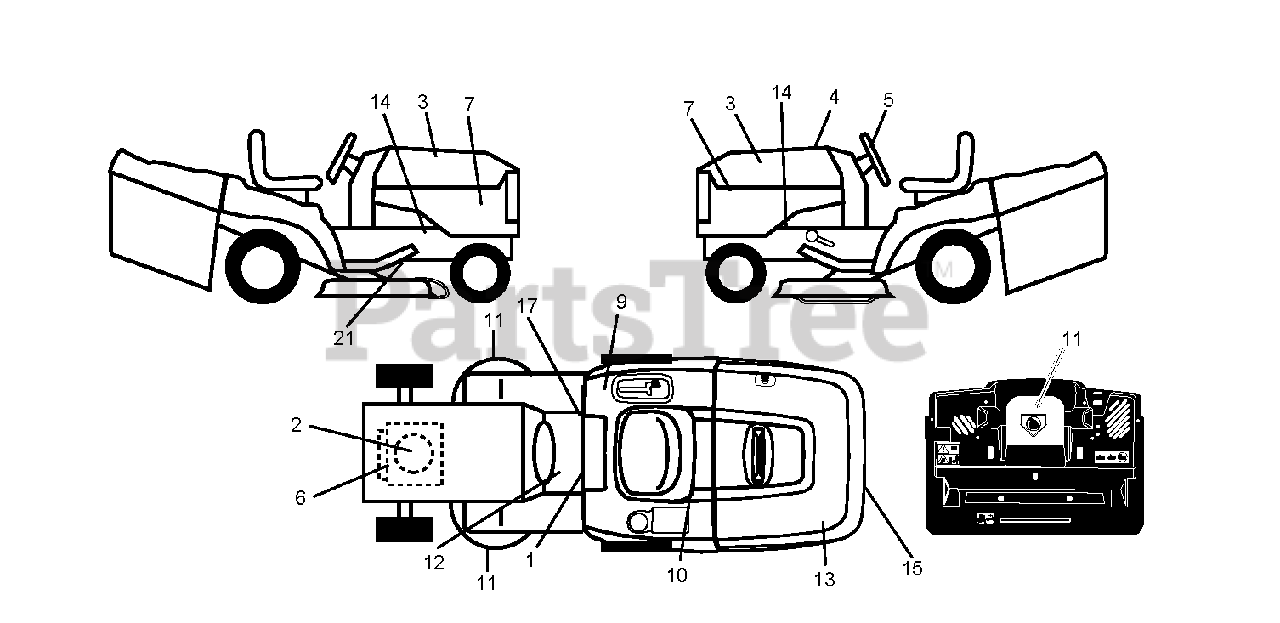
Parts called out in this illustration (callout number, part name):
10	DECAL BTRY SYMBOLS
11	DECAL.INTERNATIONL.CUTFINGER
17	DECAL PARK BRAKE
